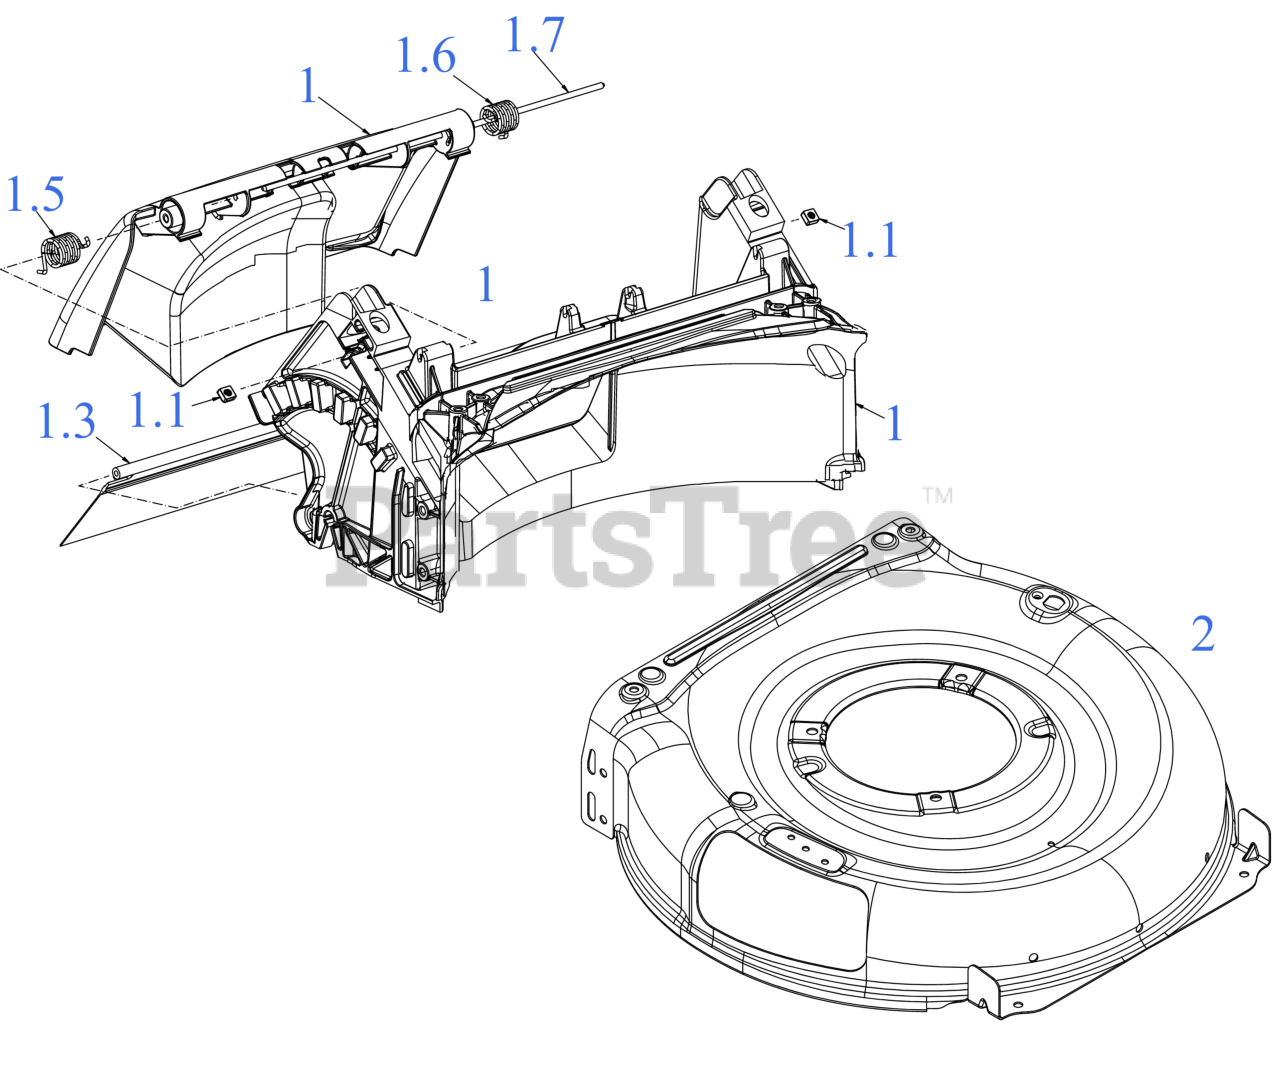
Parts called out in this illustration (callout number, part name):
1	REAR DOOR & BAFFLE ASSEMBLY
1.1	SQUARE NUT 1/4-20
1.3	TRAILSHIELD
1.5	TORSION SPRING (RH)
1.6	TORSION SPRING (LH)
1.7	REAR DOOR PIVOT ROD
